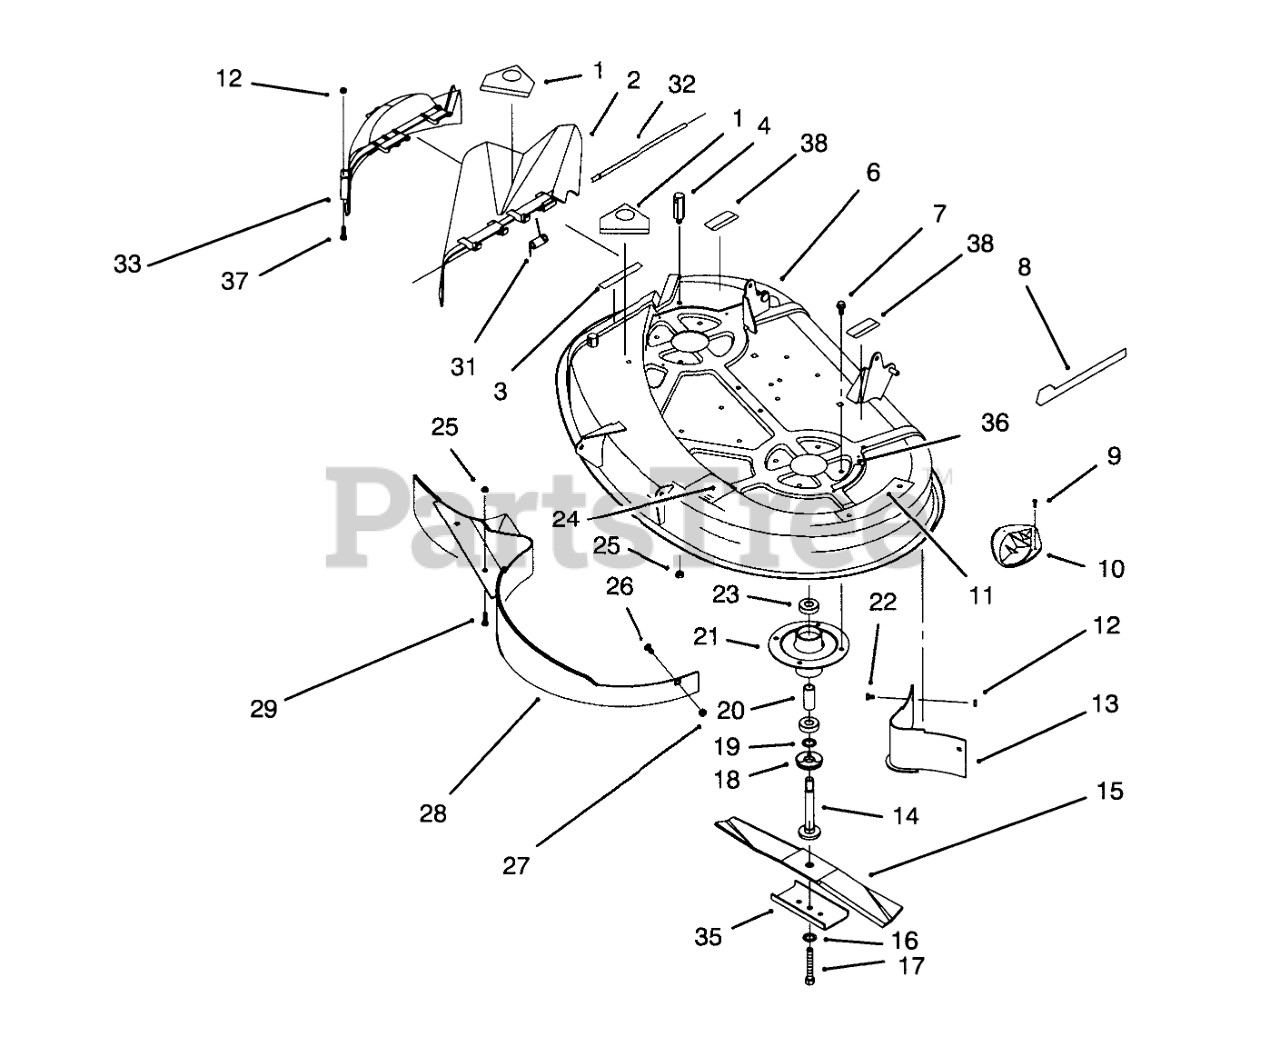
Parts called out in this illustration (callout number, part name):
1	DECAL-DANGER
2	Deflector Ass-y (Incl. Ref. #1)
3	DECAL-DANGER, DEFLECTOR
4	REAR PIVOT POST (PLTD)
6	Deck-38"
7	SCREW-TAPTITE
8	DECAL-RECYCLER DECK 38"
9	SCREW-PPH
10	PLATE-KICKER
11	DECAL-DANGER
12	NUT-LOCK, NI
13	Baffle-Rear
14	SHAFT-SPINDLE
15	Blade
16	WASHER-BELLEVILLE
17	SCREW-HH
18	SHIELD-BEARING
19	SPACER
20	SPACER
21	HOUSING-SPINDLE
22	SCREW-HH
23	BEARING-BALL
24	DECAL-ROUTING, BELT
25	NUT-LOCK, NI
26	BOLT-CARR
27	NUT-LOCK, NI
28	Baffle-38"
29	SCREW-HH
31	SPRING
32	ROD-HINGE DEFLECTOR
33	COVER-RECYCLER
35	Stiffener
36	DECAL-DANGER, SHIELD
37	SCREW-HH
38	DECAL-WARNING
